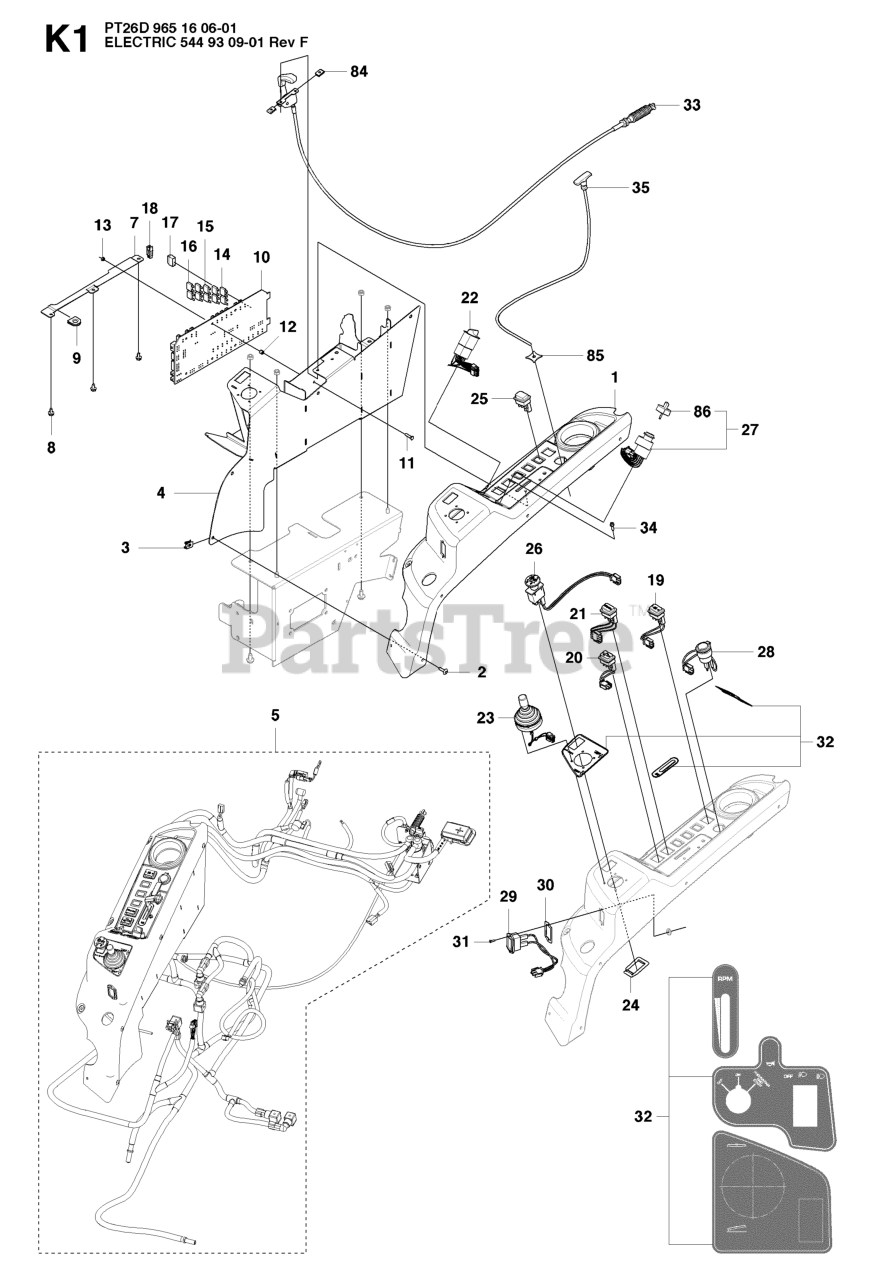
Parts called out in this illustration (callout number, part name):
8	SCREW EHHFM
11	SCREW M6S 5X20
13	LOCKNUT M5
17	COVER FUSE HOLDER
33	THROTTLE HANDLE ASSY
